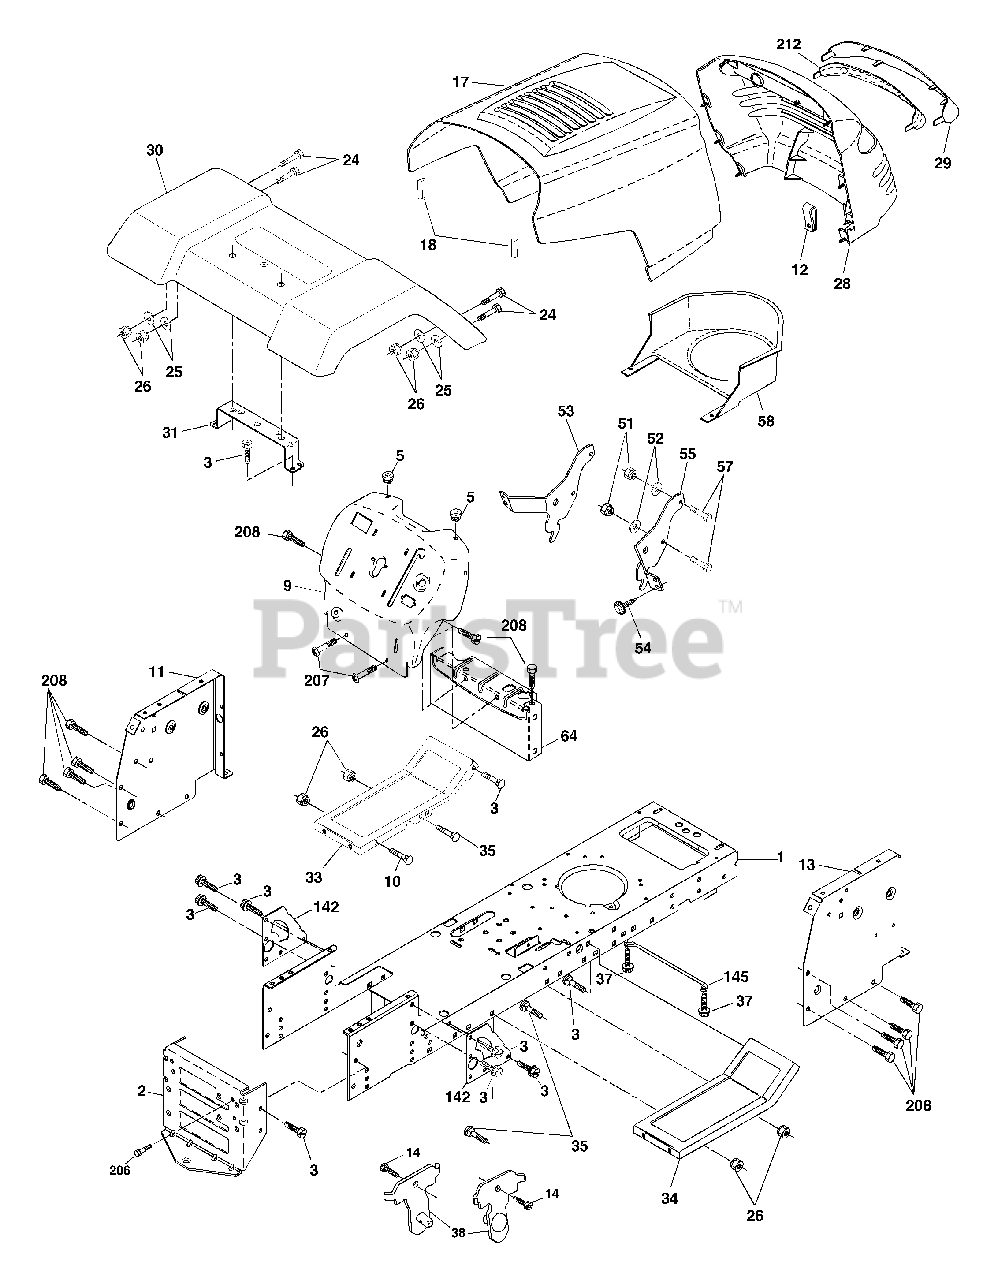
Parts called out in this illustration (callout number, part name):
1	Chassis
2	Drawbar
3	Screw 3/8-16 x 3/4
4	Screw Thdrol 3/8-16 x 1/2
5	Bumper Hood/Dash
10	Bolt Rd Hd Sqnk. 3/8-16 Unc x 1
11	Panel Asm. Dash Lh
12	Clip Tinnerman Grile P/L
13	Panel Dash Rh
14	Screw Thdrol 3/8-16 x 1/2
17	Hood
18	Bumper Hood
24	Bolt Fin Hex 3/8-16 Unc x 1 Gr. 5
25	Washer 13/32 x 13/16 x 12 Ga.
26	Nut Lock Hex w/Insert 3/8-16 UNC
28	Grill/Lens Asm
29	Lens Grille Private label
30	Fender Asm
31	Bracket Fender
33	Footrest LH
34	Footrest RH
35	Bolt Rd Hd Sht. Sqnk. 3/8-16 x 3/4
37	Screw Thdrol 5/16-18 x 1/2 Tyt
38	Bracket Asm. Pivot Mower Rear
51	Nut Lock Hex W/Ins. 1/4-20
52	Washer 9/32 x 7/8 x 16 Ga.
53	Bracket Grille LH
54	Screw Hex Wshd 8-18 x 7/8
55	Bracket, Grille RH
57	Bolt Fin Hex 1/4-20 x .75
58	Air Duct Private Label
64	Dash Lower
142	Plate Reinforcement
145	Rod Pivot Chassis/Hood
206	Bolt shoulder 5/16-18
207	Screw Thdrol 5/16-18 x 1/2
208	Screw Thdrol 3/8-16 x 1/2
212	Insert Lens Reflector
